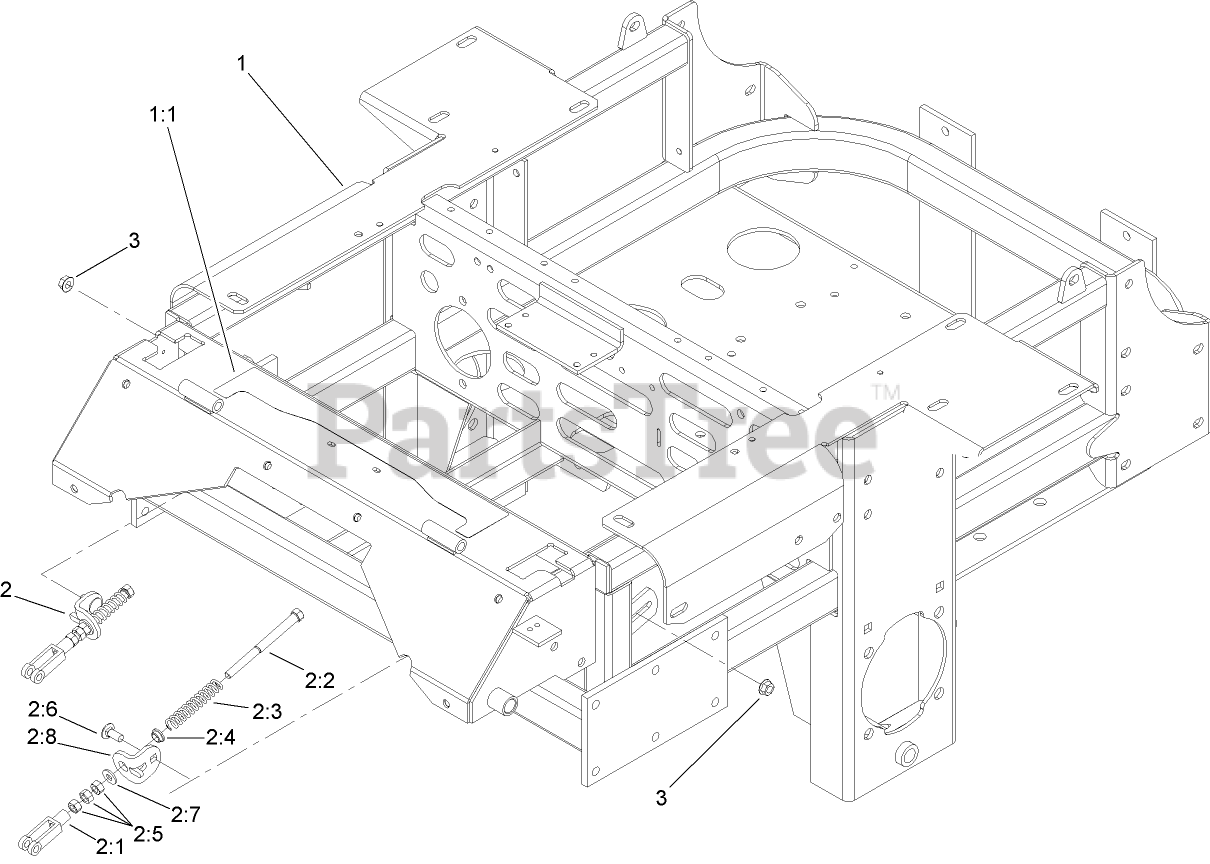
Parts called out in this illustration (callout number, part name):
1	MAIN FRAME ASM
1:1	DECAL-CONSOLE, TOP
2	NEUTRAL RETURN ASM
2:1	YOKE-ADJUSTABLE
2:2	BOLT-RETURN, NEUTRAL
2:3	SPRING-RETURN, NEUTRAL
2:4	BUSHING-NYLON, FLANGED
2:5	NUT-HEX
2:6	SCREW-CARR
2:7	WASHER-FLAT
2:8	TAB-ADJUSTMENT
3	NUT-HF
